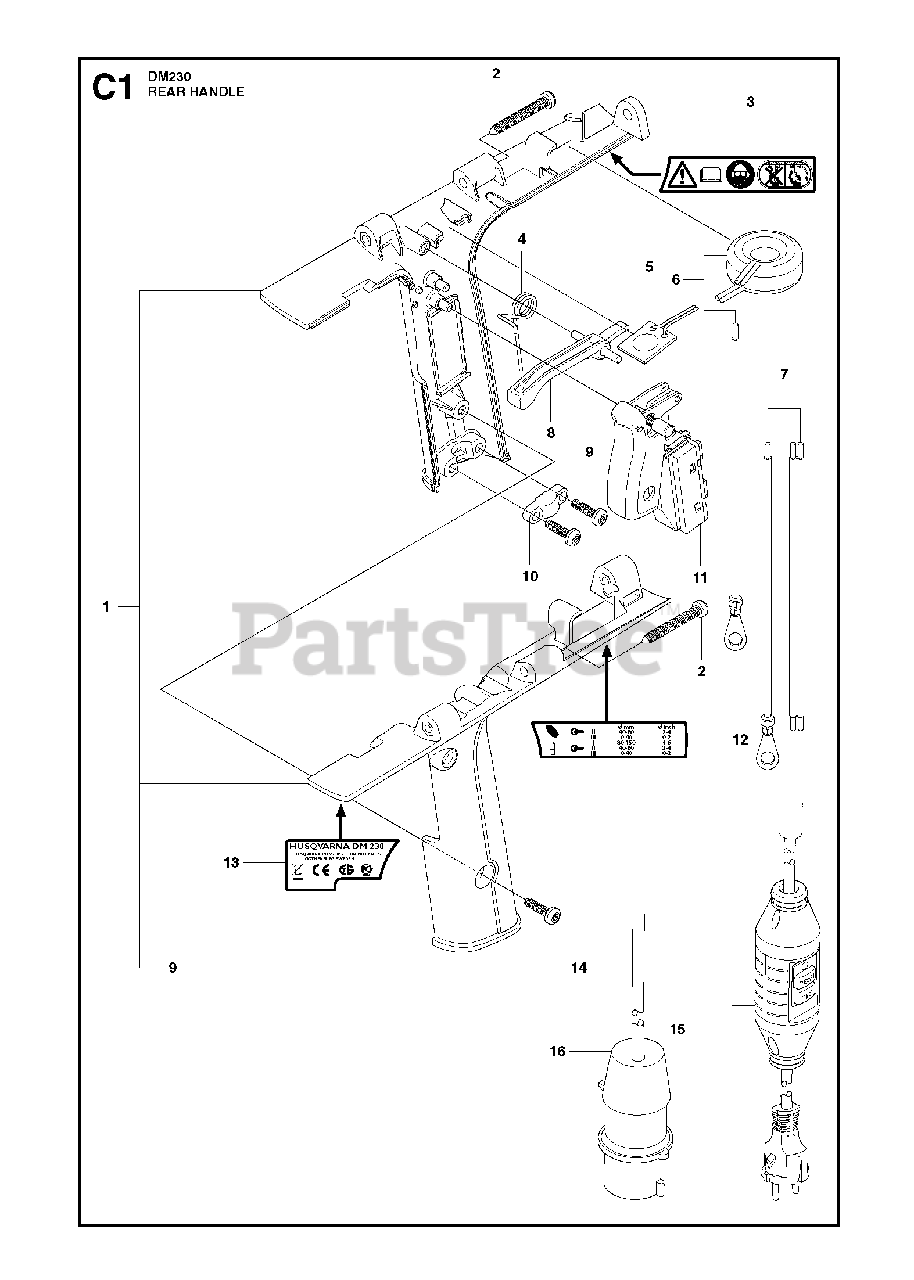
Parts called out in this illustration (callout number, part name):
14	CABLE110V
15	CABLE230V, Incl. PRCD 10 mA, EU
15	CABLE120V, Incl. PRCD 6 mA, USA
15	CABLE230V, Incl. PRCD 10 mA, AUS
